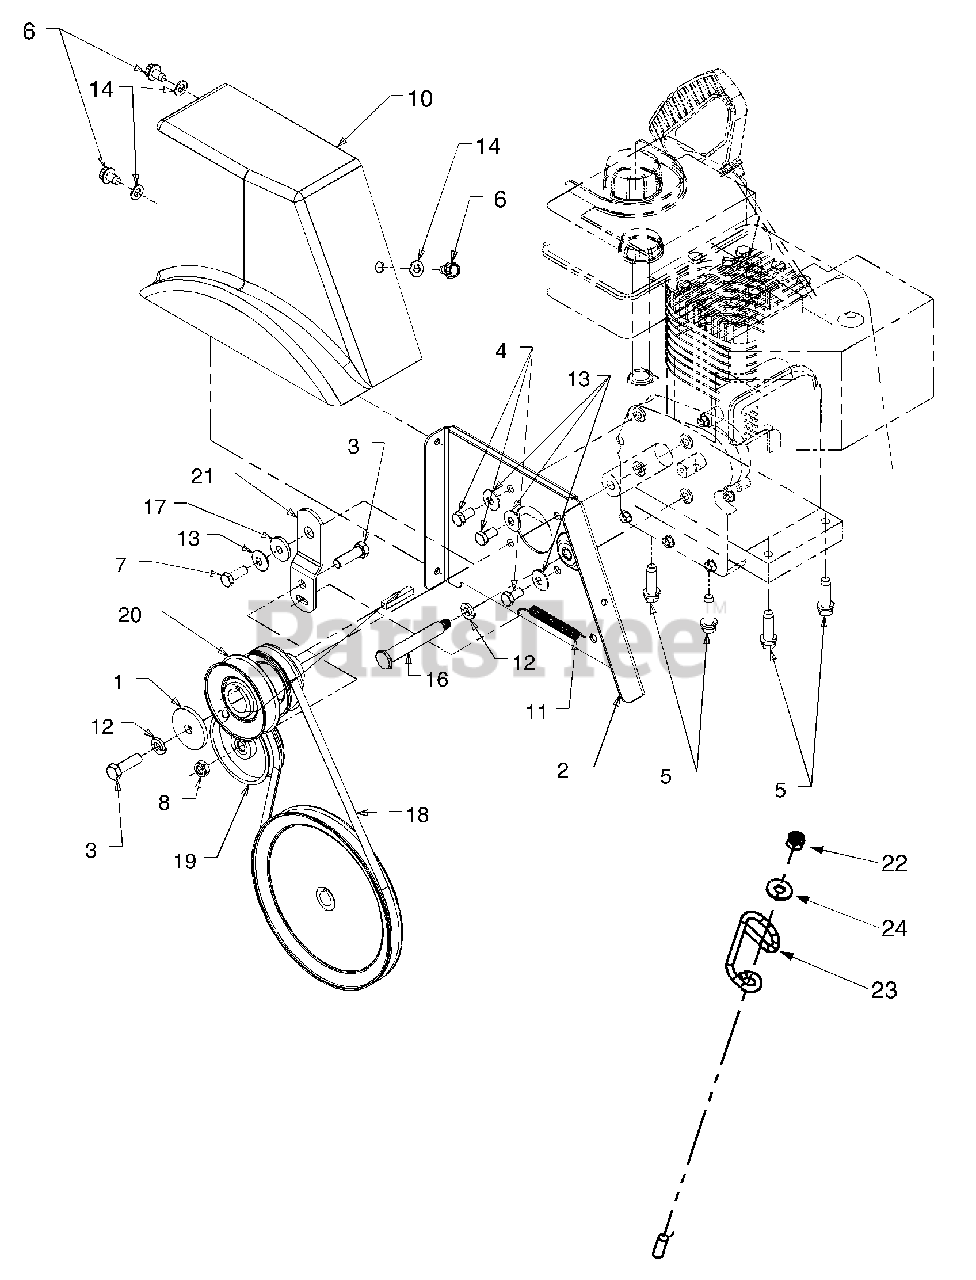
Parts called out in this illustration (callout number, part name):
1	Wash:.390 ID x 1.75 O.D.
4	Hex Hd. Screw 5/16-4 x .625 (Gr.5)
5	Hex TT-Sems Screw 3/8-16 x 1.25
6	Hex TT-Tap Screw 5/16-18 Thd.
7	Hex Lock Screw 5/16-24 x .875
8	Jam Nut 3/8-24 Thd.
10	Cvr:Belt
11	Spring:Extension
12	L-Wash .3/8
13	Bell-wash. .340 I.D. x .872 O.D.
14	Washer:Flat
16	Shoulder Screw
17	Shoulder Spacer
18	V-Belt
19	Idler:Flat
20	Double Pulley
21	Idler:Brkt
22	Hex Lock Nut 1/4-20 Thd.
23	Cable Control Wire
24	Fl-Wash. .28 x .74 x .063
